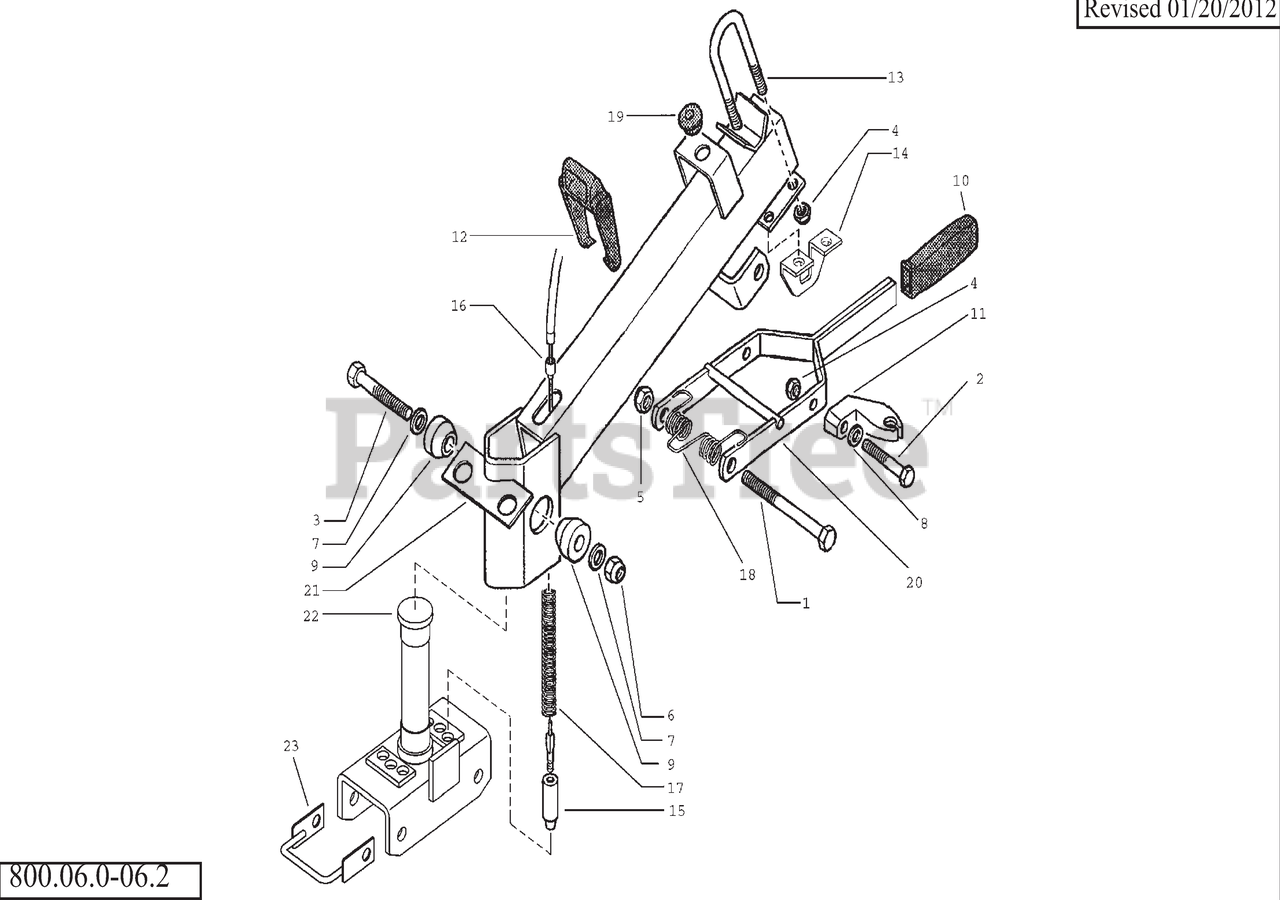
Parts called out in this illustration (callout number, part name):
1	CAP SCREW, M10X110
2	CAP SCREW, M8X40
3	CAP SCREW, M12X80
4	NUT, SELF LOCKING, M8
5	NUT, SELF LOCKING, M10
6	NUT, LOCK DEFORMED, M12
7	SPRING
8	WASHER, LOCK, M8.4
9	WEDGE
11	SUPPORT, CONTROL ROD
12	GUIDE, CABLE
13	U-BOLT
14	BRACKET
16	SHEATH END
17	SPRING, STEERING COLUMN
18	SPRING, HANDLEBAR RELEASE
19	SUPPORT, CAP
20	LEVER, HANDLEBAR SELECTION
21	STEERING COLUMN
22	COUPLER, STEERING COLUMN
23	LOOP
